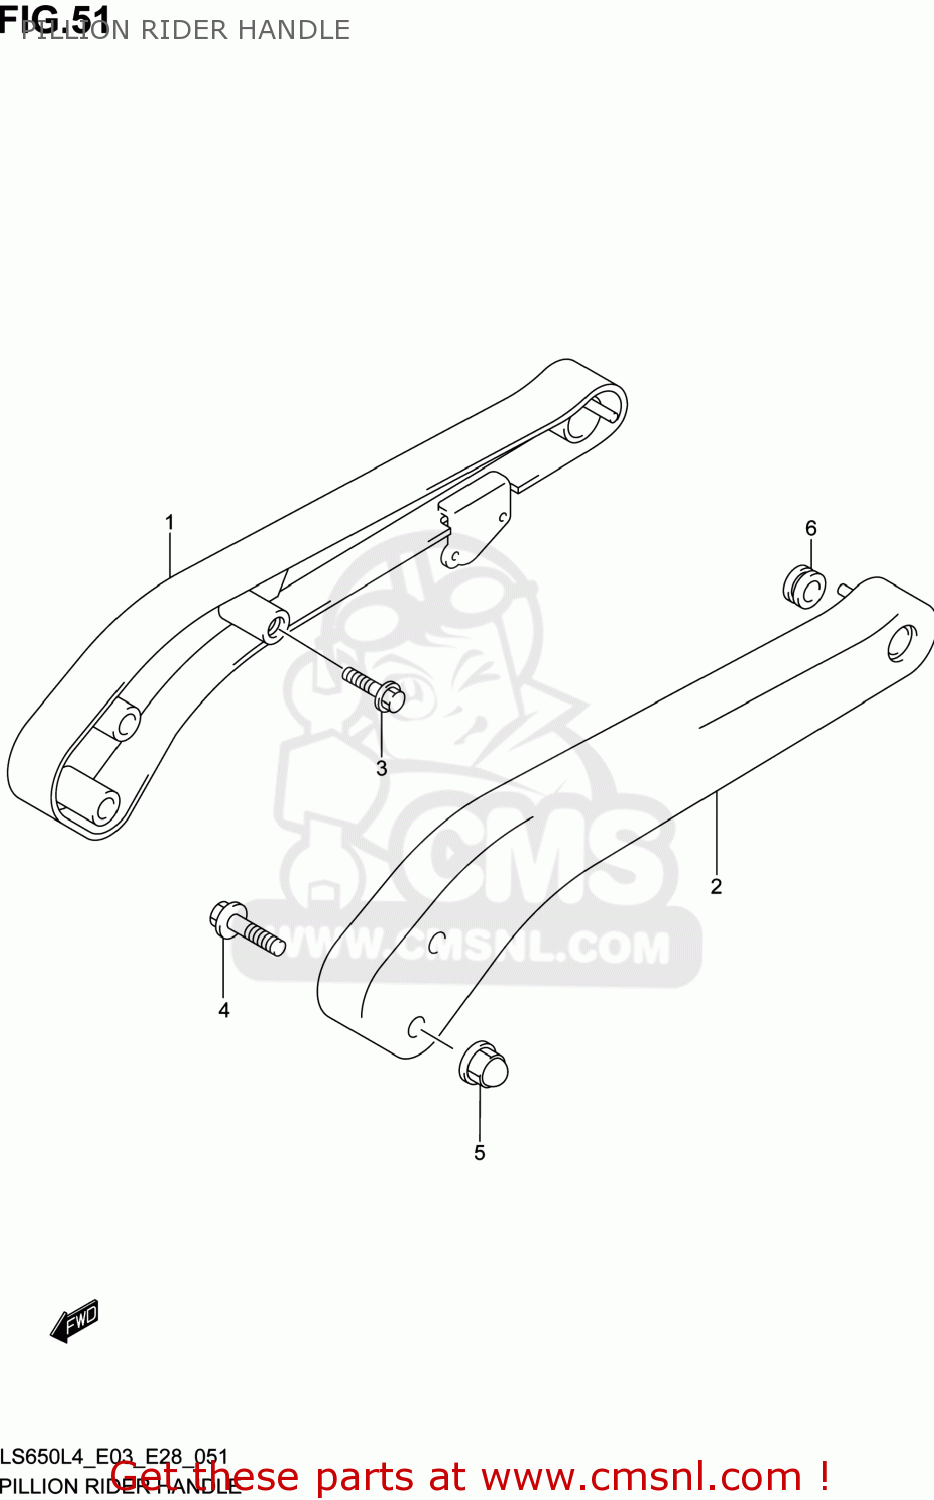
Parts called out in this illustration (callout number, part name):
1	HANDLE,PILLION RIDER,R
2	HANDLE,PILLION RIDER,L
3	BOLT
4	BOLT
5	NUT
6	CUSHION
